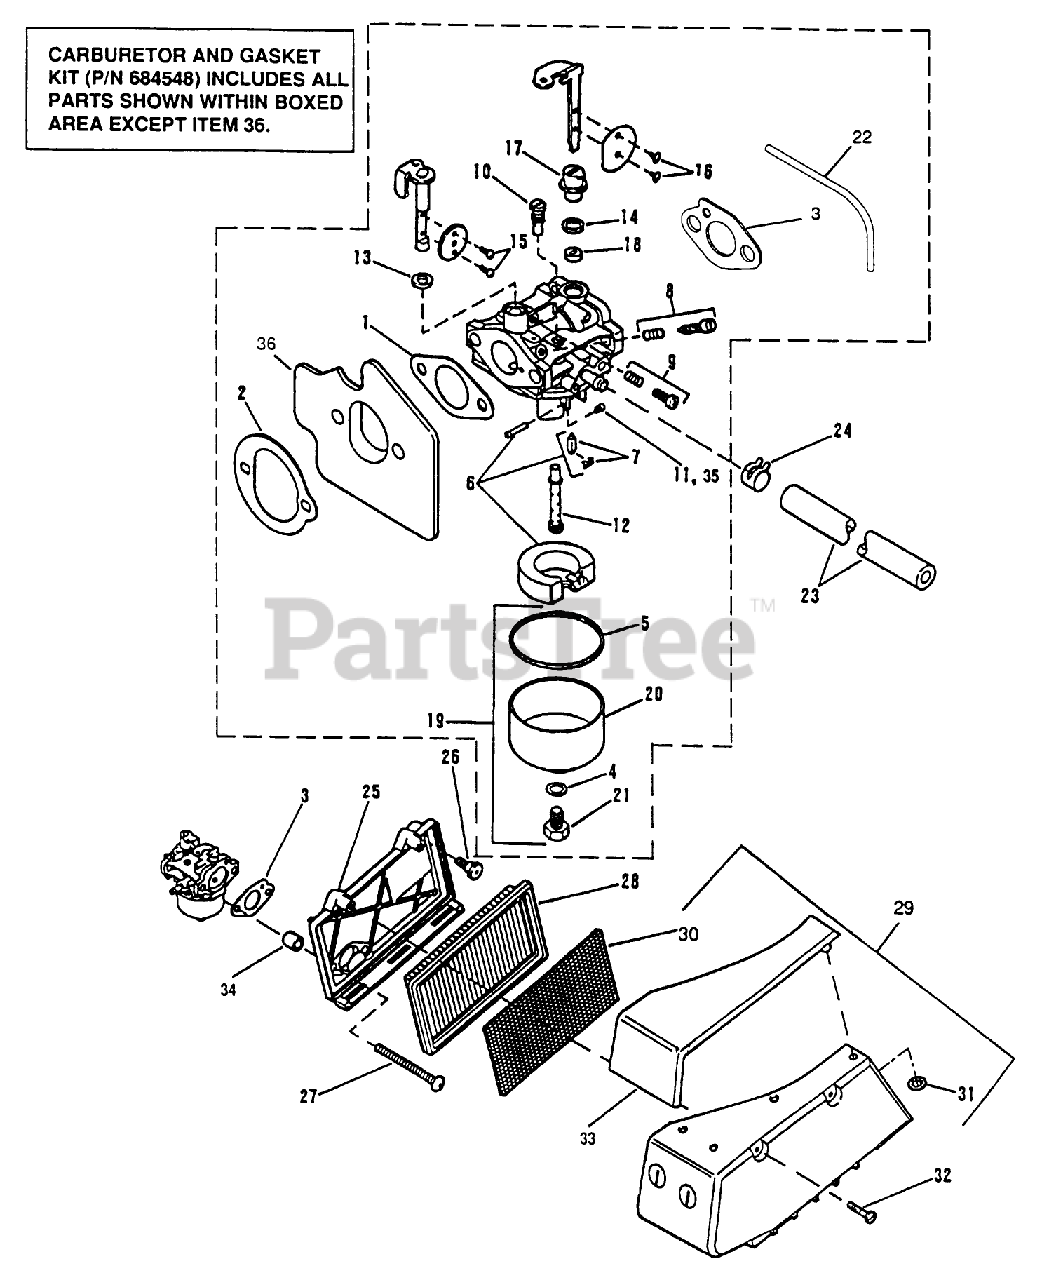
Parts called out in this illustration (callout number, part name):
1	GASKET SM
2	GASKET SM
3	GASKET-FIL SM
4	GASKET-BOWL RET S
5	GASKET-FUELBOWL S
7	NEEDLE & CLIP S
10	PILOT JET
11	CARB JET
14	SEAL CHOKE SHAFT
16	SCREW CHOKE VALVE
21	SCREW,BOWL RET S
22	HOSE-CARB.VENT SM
23	GAS LINE SM
24	HOSE CLAMP SM
28	ELEMENT-AIR SM
29	AIR FILTER COVER
31	NUT-PUSH
35	MAIN JET
36	SPACER & NOZZ SM
